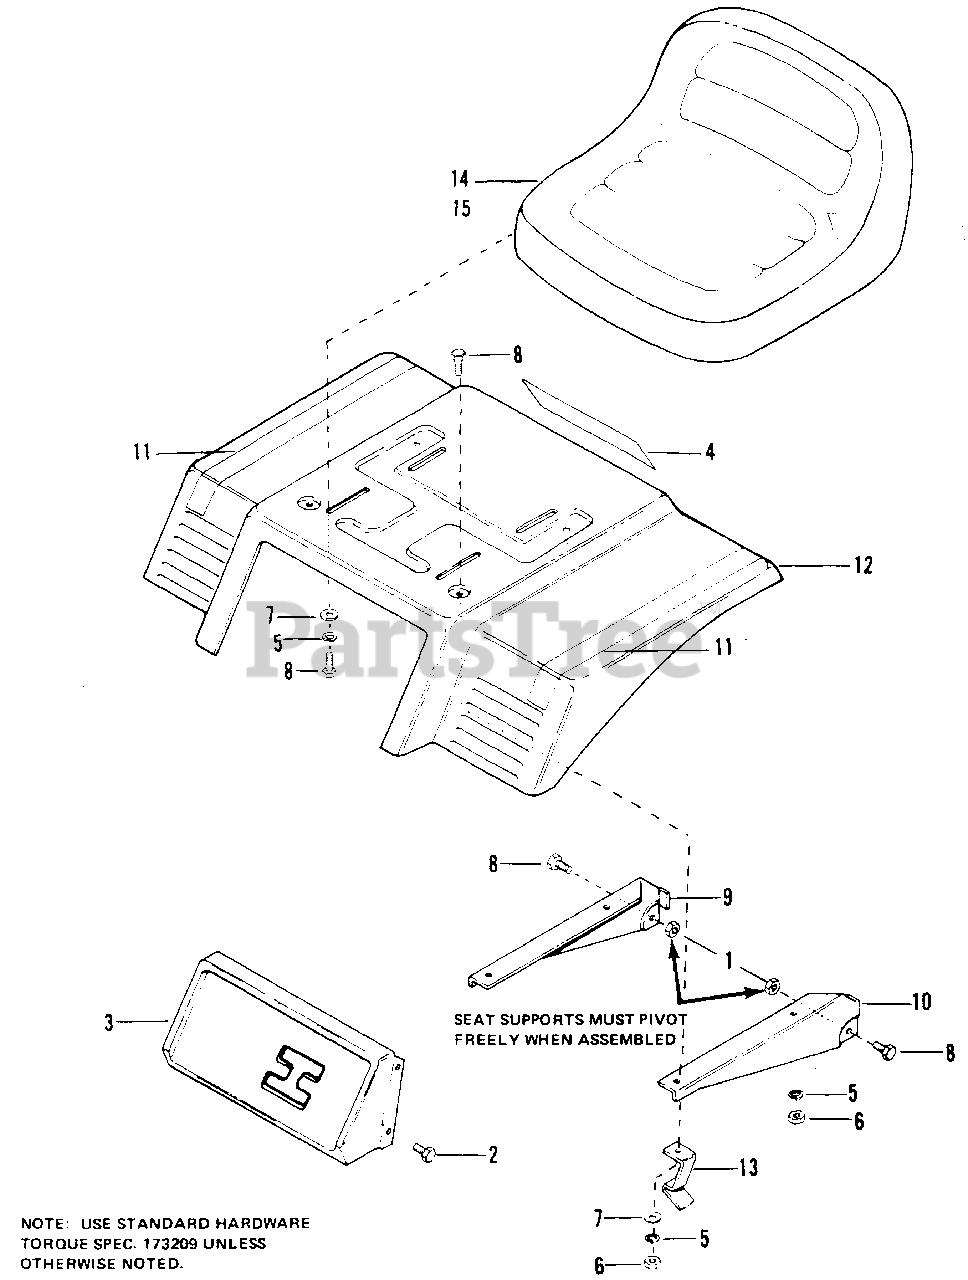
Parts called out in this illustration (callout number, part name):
1	NUT, Hex Lock, 5/16-18
2	SCREW, Taptite, Washer Hd., 1/4-20 x 1/2
3	PANEL, Shift
4	DECAL, Simplicity
5	LOCKWASHER, Spring, 5/16
6	NUT, Hex, 5/16-18
7	WASHER, Plain, 5/16
8	CAPSCREW, Hex Hd., 5/16-18 x 3/4
9	SUPPORT, R.H., Seat
10	SUPPORT, L.H., Seat
11	DECAL, Seat Deck
12	DECK, Seat
13	LATCH, Spring
14	SEAT ASSY (4108 MS Only)
15	SEAT ASSY (4108ES & 4111 Only)
